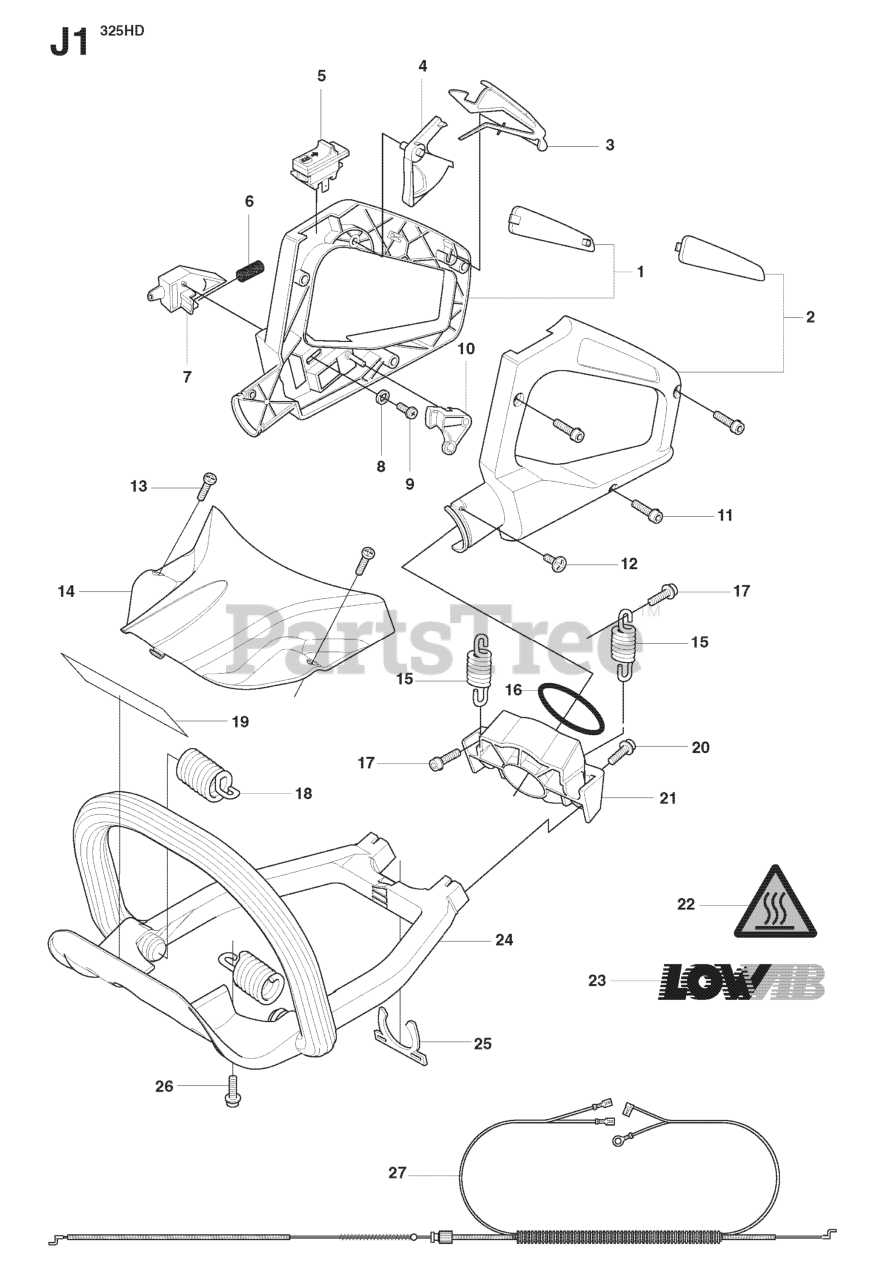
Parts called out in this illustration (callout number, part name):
1	REAR HANDLE COMPLETE
2	HANDLE PART
3	THROTTLE LOCK
4	THROTTLE TRIGGER
5	STOP BUTTON
14	HEAT PROTECTOR EXHAUST PIPE
15	VIBRATION ABSORBER
18	VIBRATION ABSORBER
